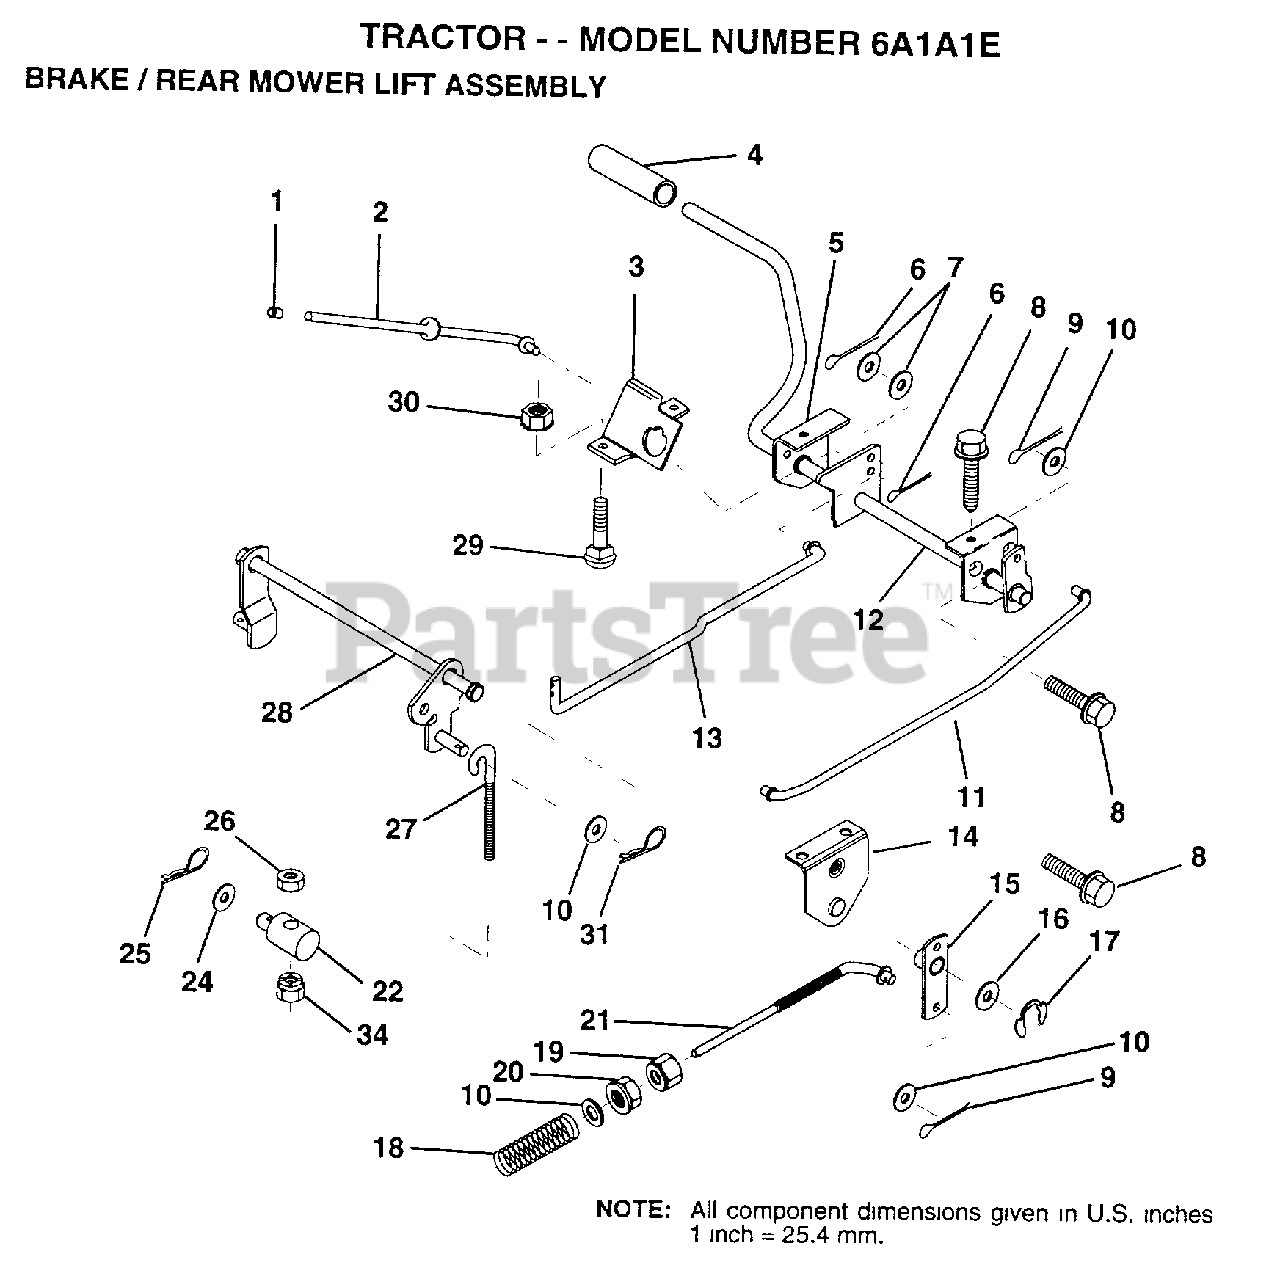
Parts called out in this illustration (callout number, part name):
1	PLUNGER CAP T
2	"ROD,PARK BRAKE"
3	"BRKT,PARK BRAKE"
4	FOOT PEDAL COVER
5	"BRKT,CLU PEDAL LH"
7	WASHER
8	SCREW LT
9	COTTER PIN
10	WASHER
11	"ROD,FRT BRAKE"
12	PEDAL ASM CL/BK36
13	"ROD,CLUTCH"
14	"BRKT,LIFT SHAFT"
15	PVT BRAKE ARM ASM
16	WASHER T
17	KLIP RING
18	SPRING ROD BRAKE
19	NUT
20	NUT
22	TRUNNION.LIFT.
24	WASHER
25	SPRING.RETAINER
26	LOCKNUT
27	"LINK, MOWER REAR"
28	LIFT ASM MOW REAR
31	RETAINER.SPRING
